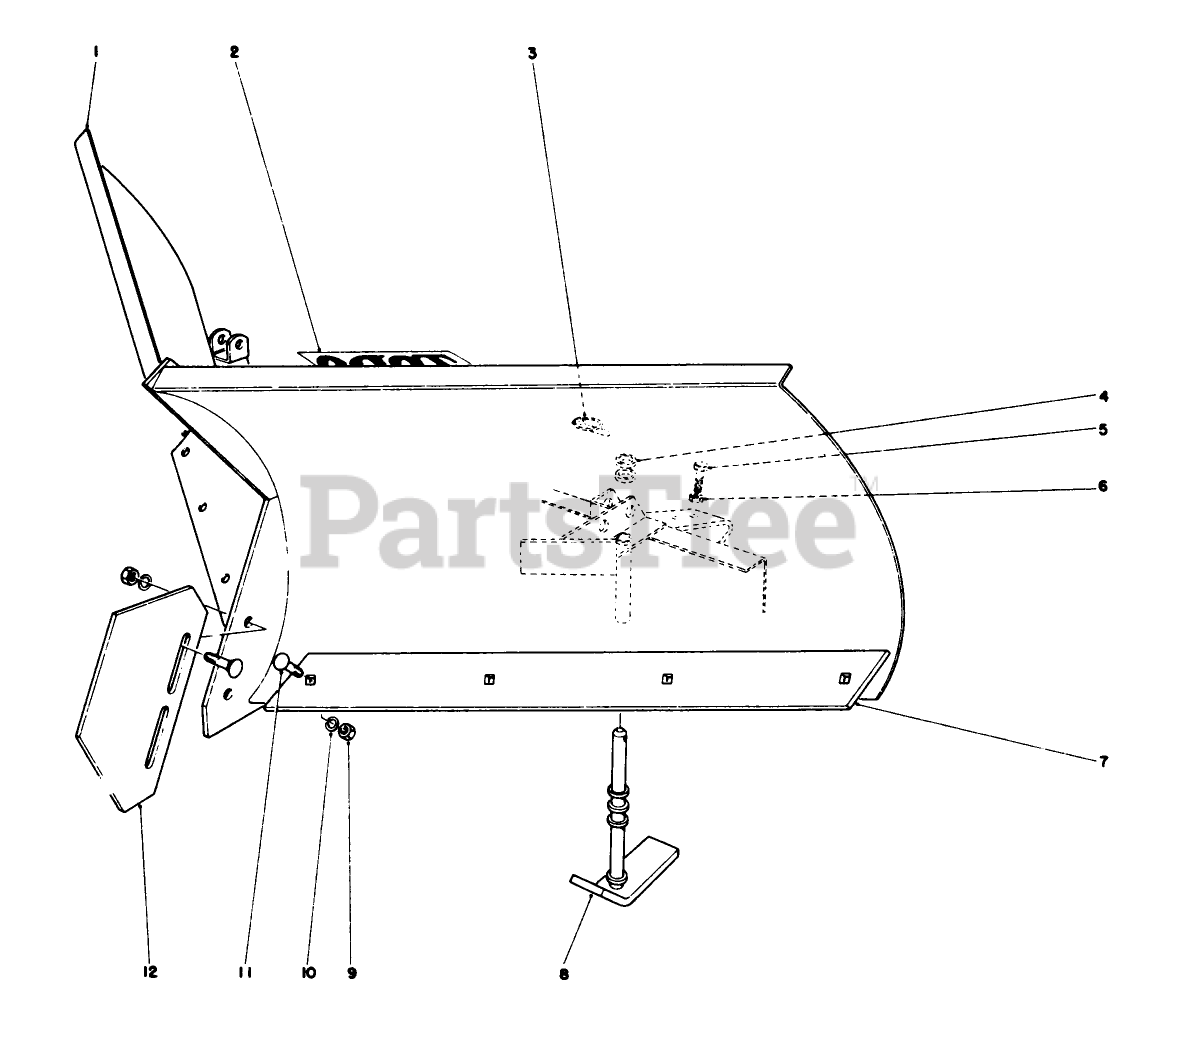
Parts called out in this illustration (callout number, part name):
1	V-Plow
2	Decal
3	PIN-LYNCH
4	SPACER TUBE B
5	SCREW-HH
6	NUT-JAM
7	Blade-Scraper
8	Skid
9	NUT-HH
10	WASHER-LOCK
11	SCREW-CARR
12	Nose Skid
